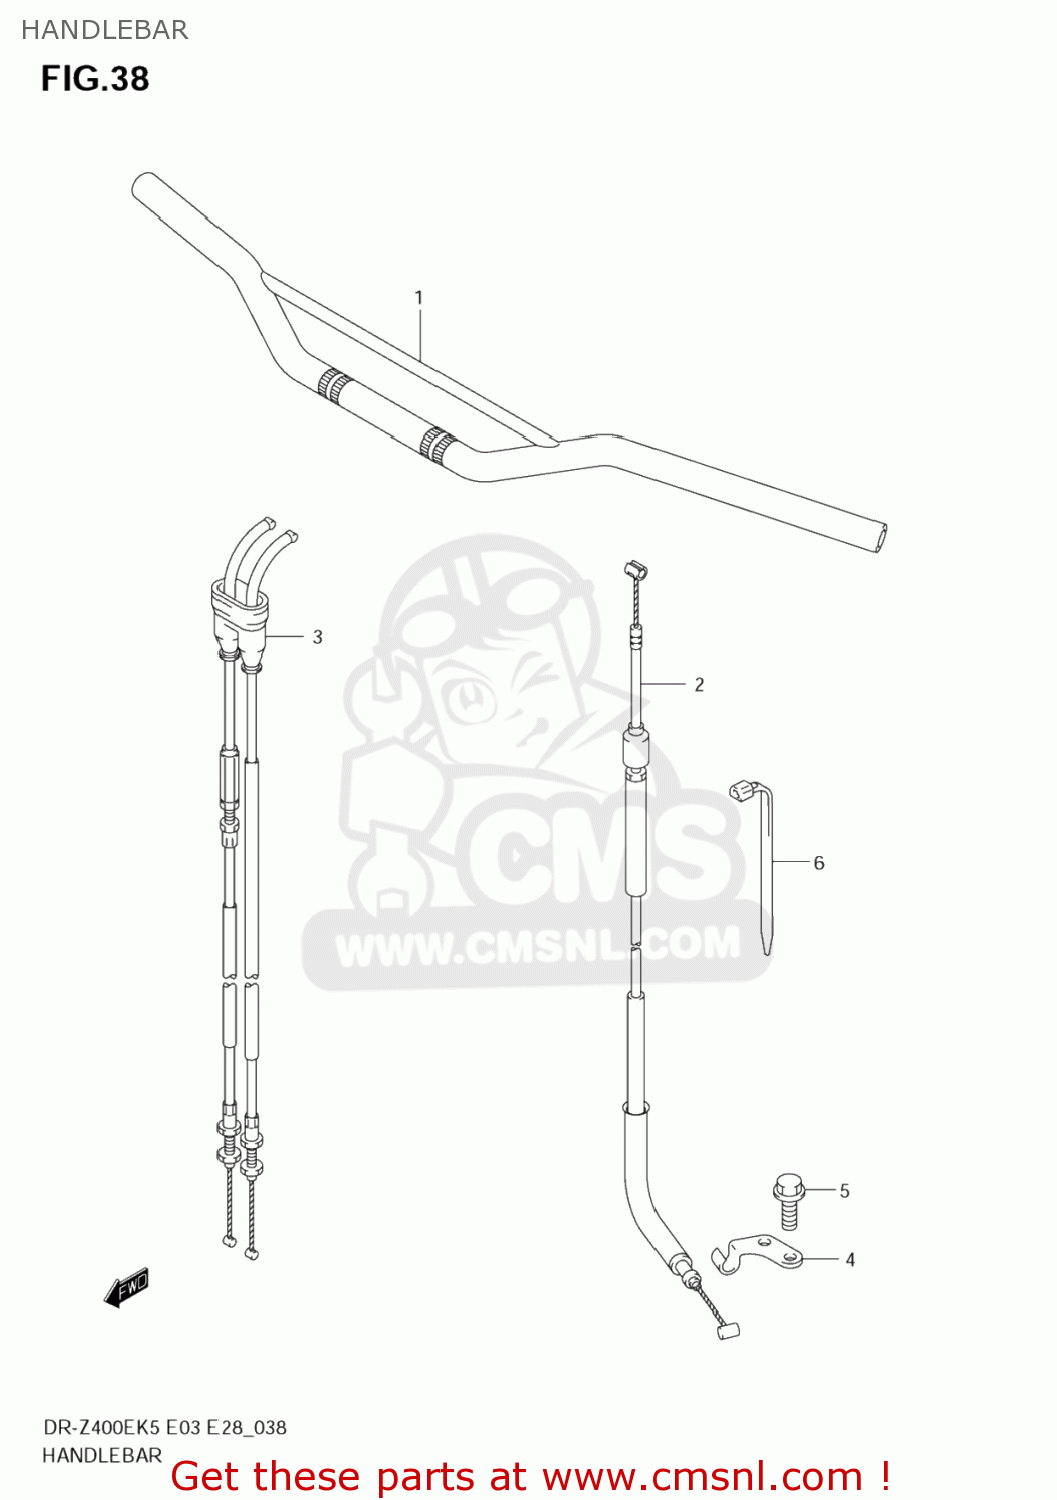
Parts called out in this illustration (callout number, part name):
1	HANDLEBAR(SILVER)
2	CABLE ASSY,CLUTCH
3	CABLE SET,THROTTLE
4	STOPPER,CLUTCH CABLE
5	BOLT
6	CLAMP(L:235)
